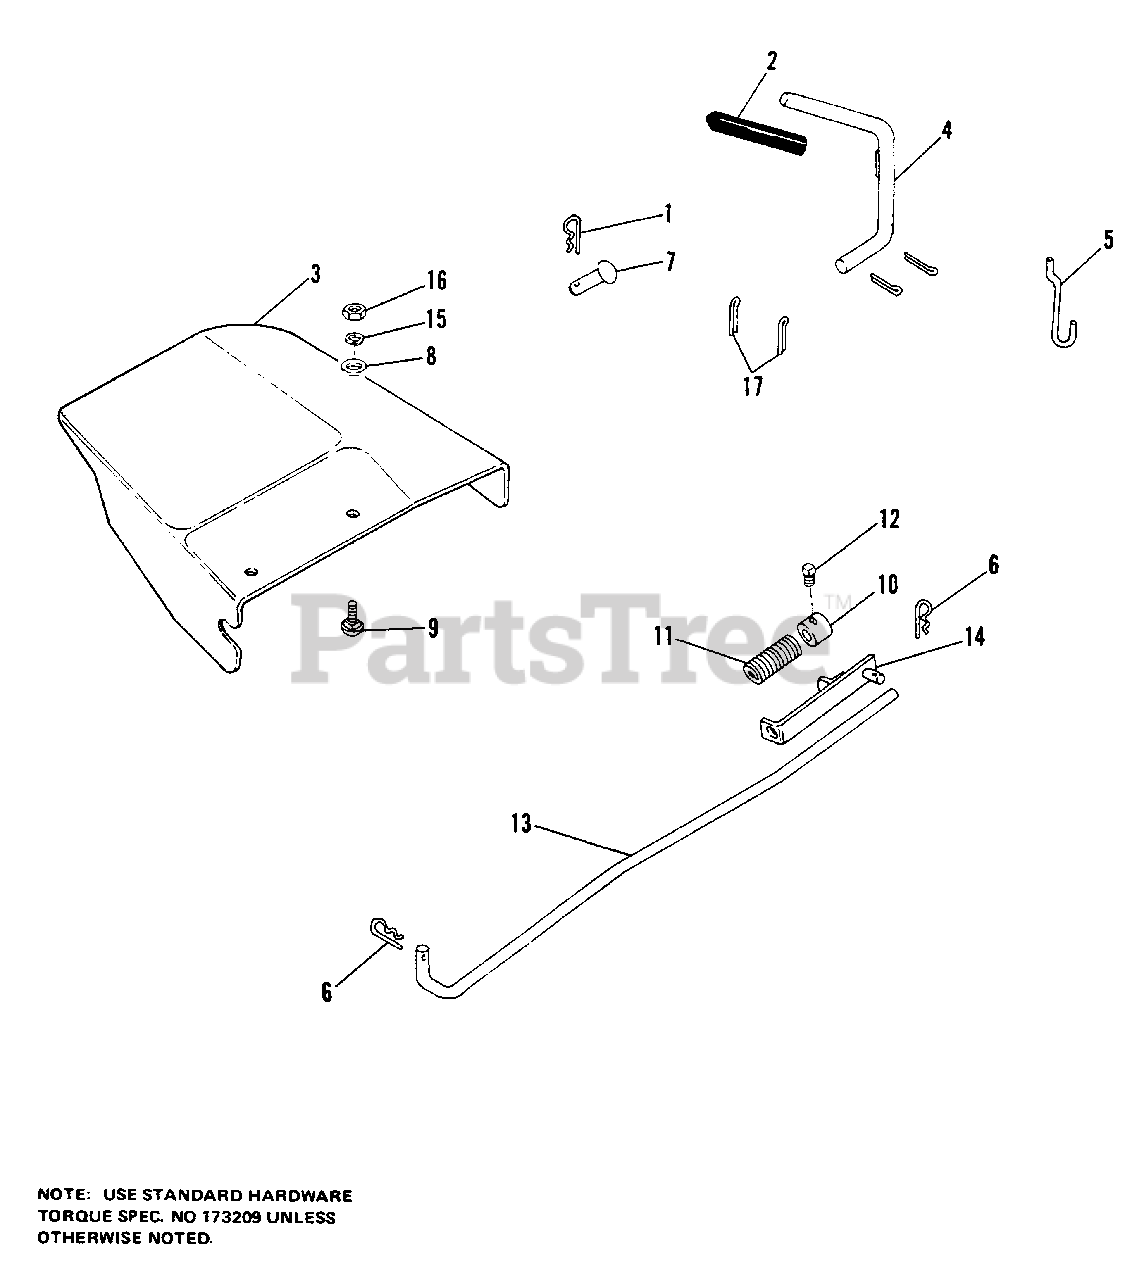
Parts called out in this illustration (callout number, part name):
1	CLIP, Spring
2	HANDLE, Grip
4	LEVER, Control
6	CLIP, Spring
8	WASHER, Plain, 3/8
9	BOLT, Carriage, 3/8-16 x 3/4
10	COLLAR, Set
12	SCREW, Set, Square Hd., 1/4-20 x 3/8
14	ROD GUIDE ASSY
15	LOCKWASHER, 3/8
16	NUT, Hex, 3/8
17	PIN, Cotter
